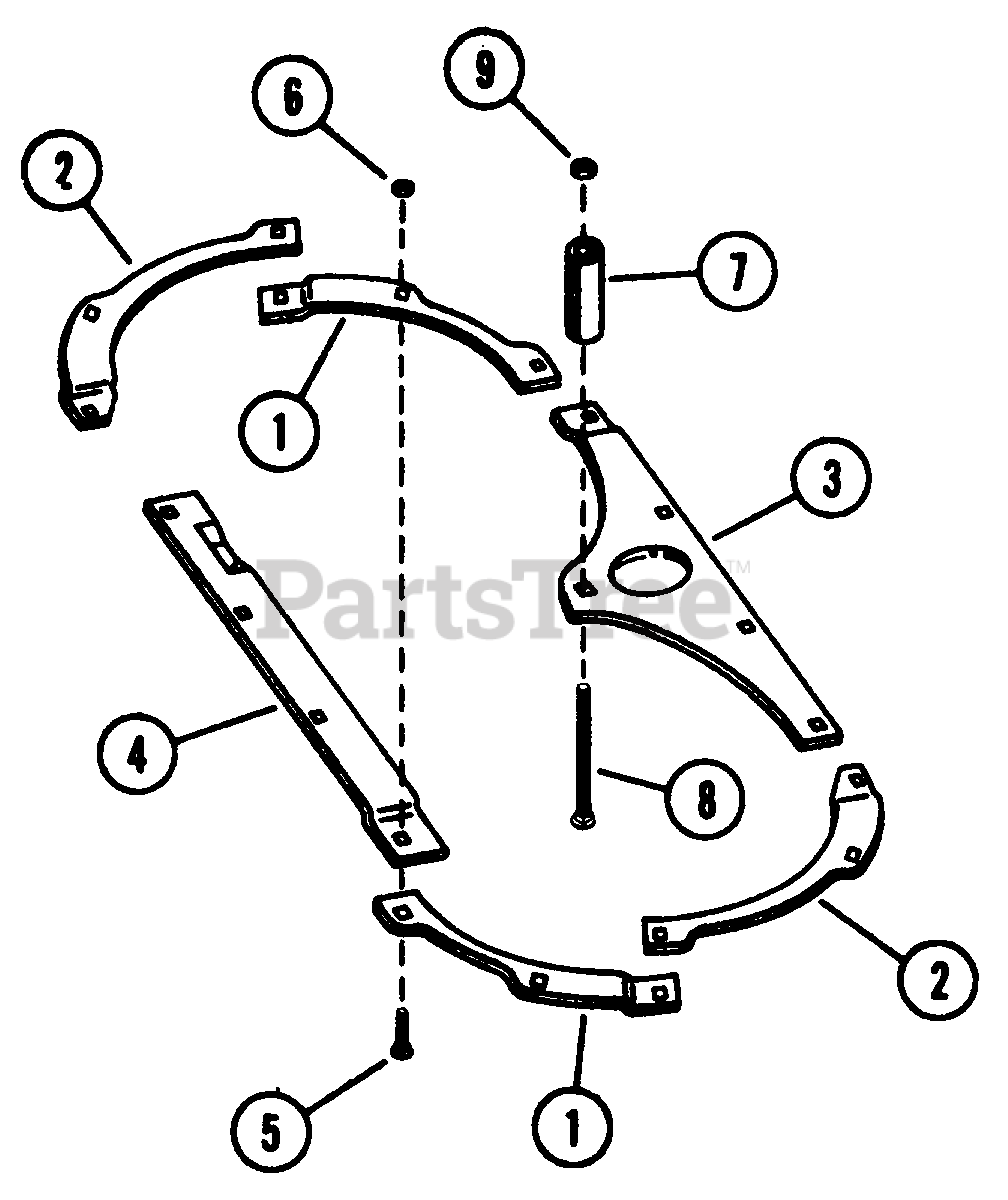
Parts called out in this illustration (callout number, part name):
1	SHORT CURVE FLANGE
2	LONG CURVE FLANGE
3	REAR FLANGE
4	FRONT FLANGE
5	BOLT, CARRIAGE 1/4-20X5/8
6	LOCKNUT 1/4-20
7	SPACER
8	BOLT, CARRIAGE 1/2-13X4
9	LOCKNUT 1/2-13
